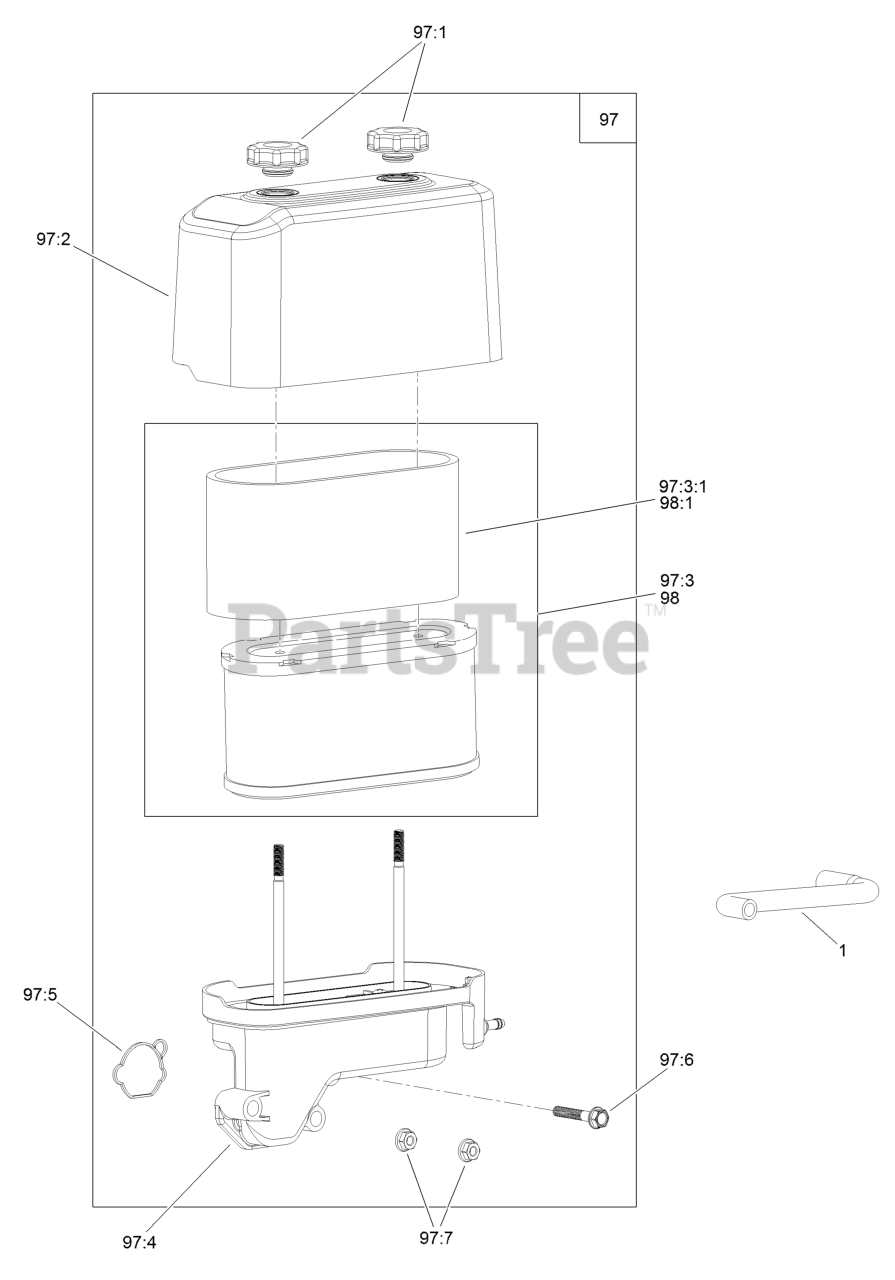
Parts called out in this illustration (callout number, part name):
1	Tube-Breather
97	Air Filter ASM
97:1	Nut-Speed
97:2	Cover-Filter, Air
97:3	Air Filter Kit
97:3:1	Prefilter
97:4	Base-Filter, Air
97:5	Gasket-Carburetor
97:6	Screw-HHF
97:7	Nut-Flange
98	Air Filter Kit
98:1	Prefilter
